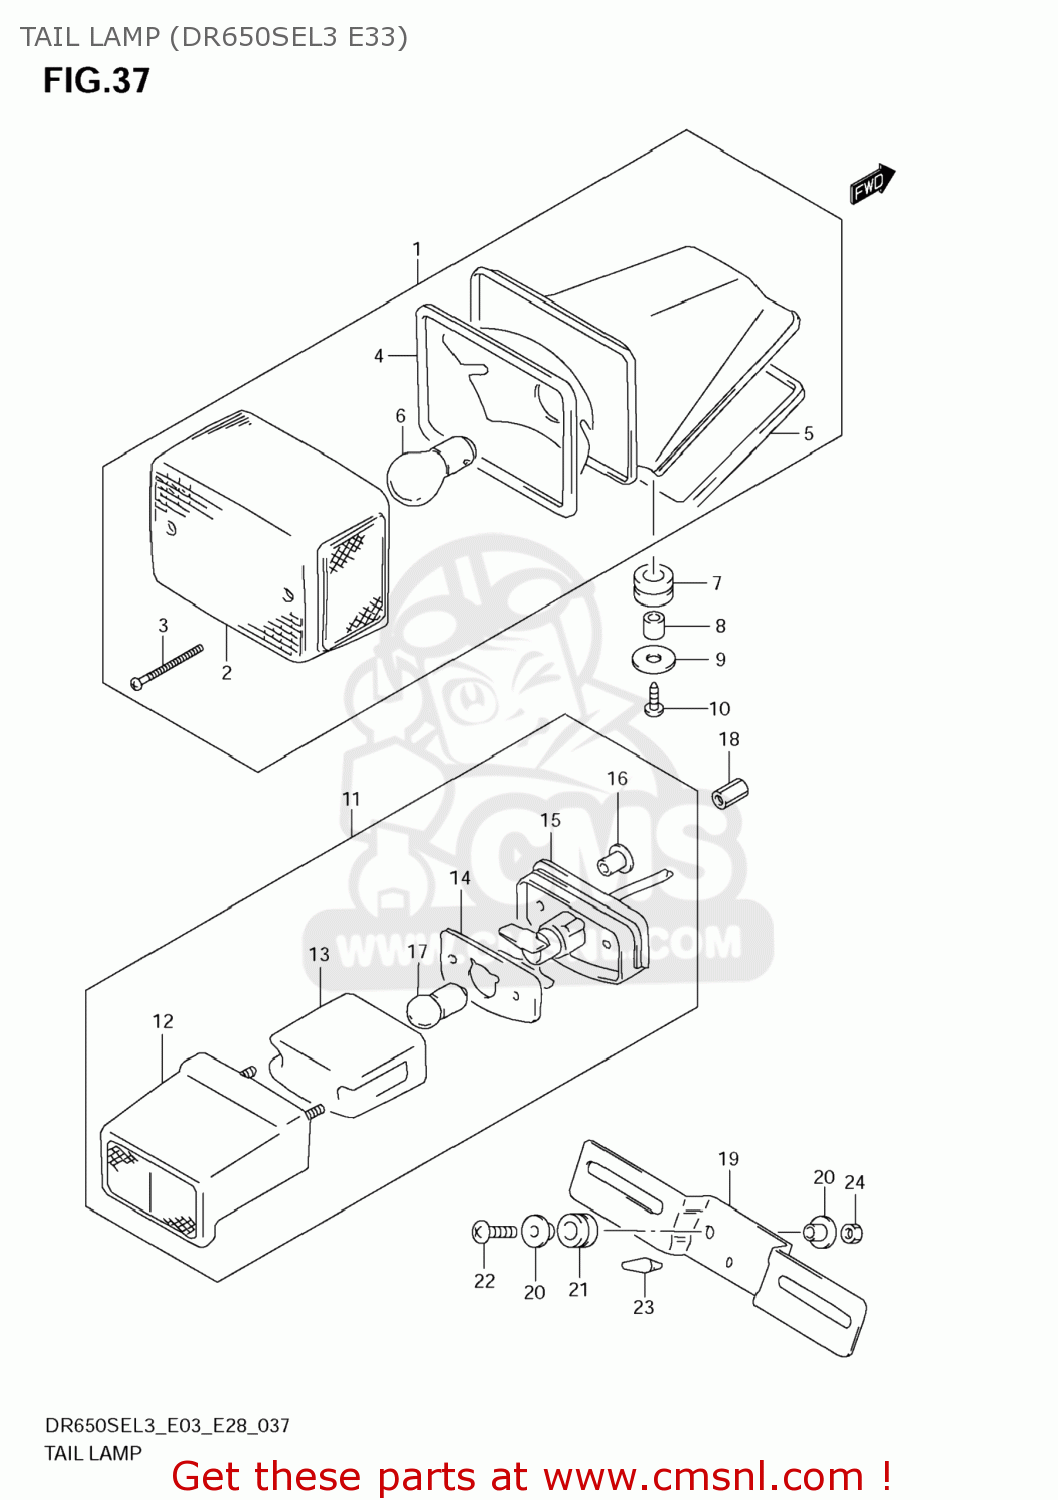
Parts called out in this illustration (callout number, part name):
1	LAMP ASSY,RR COMBINATION
2	LENS,TAIL LAMP
3	SCREW(4X45)
4	GASKET,LENS (NAS)
5	GASKET (NAS)
6	BULB(12V21/5W)
7	CUSHION
8	SPACER(6.1X8X9.5)
9	WASHER(6.5X20X1.6)
10	SCREW
11	LAMP ASSY,LICENSE
12	COVER,LICENSE
13	LENS
14	GASKET,LICENSE LAMP (NAS)
15	CUSHION
16	SPACER
17	BULB(12V5W,BF150-40160A)
18	NUT
19	BRACKET,LICENSE PLATE
20	WASHER
21	CUSHION
22	SCREW
23	CUSHION
24	NUT
